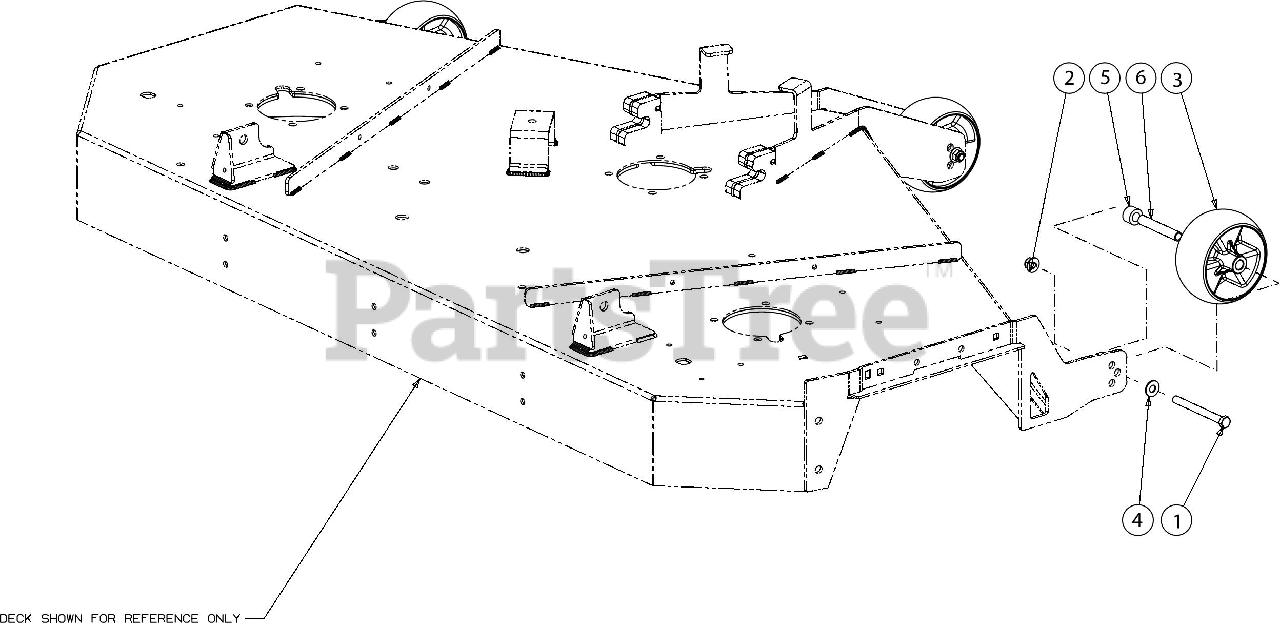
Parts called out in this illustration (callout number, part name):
1	HEX SCREW 3/8-16 X 4.00
3	DECK WHEEL
3	WHEELS-DELUXE 5"
4	FLAT WASHER
5	SPACER .502X.875X.56LG
6	SPACER .38X.49X3.05LG
